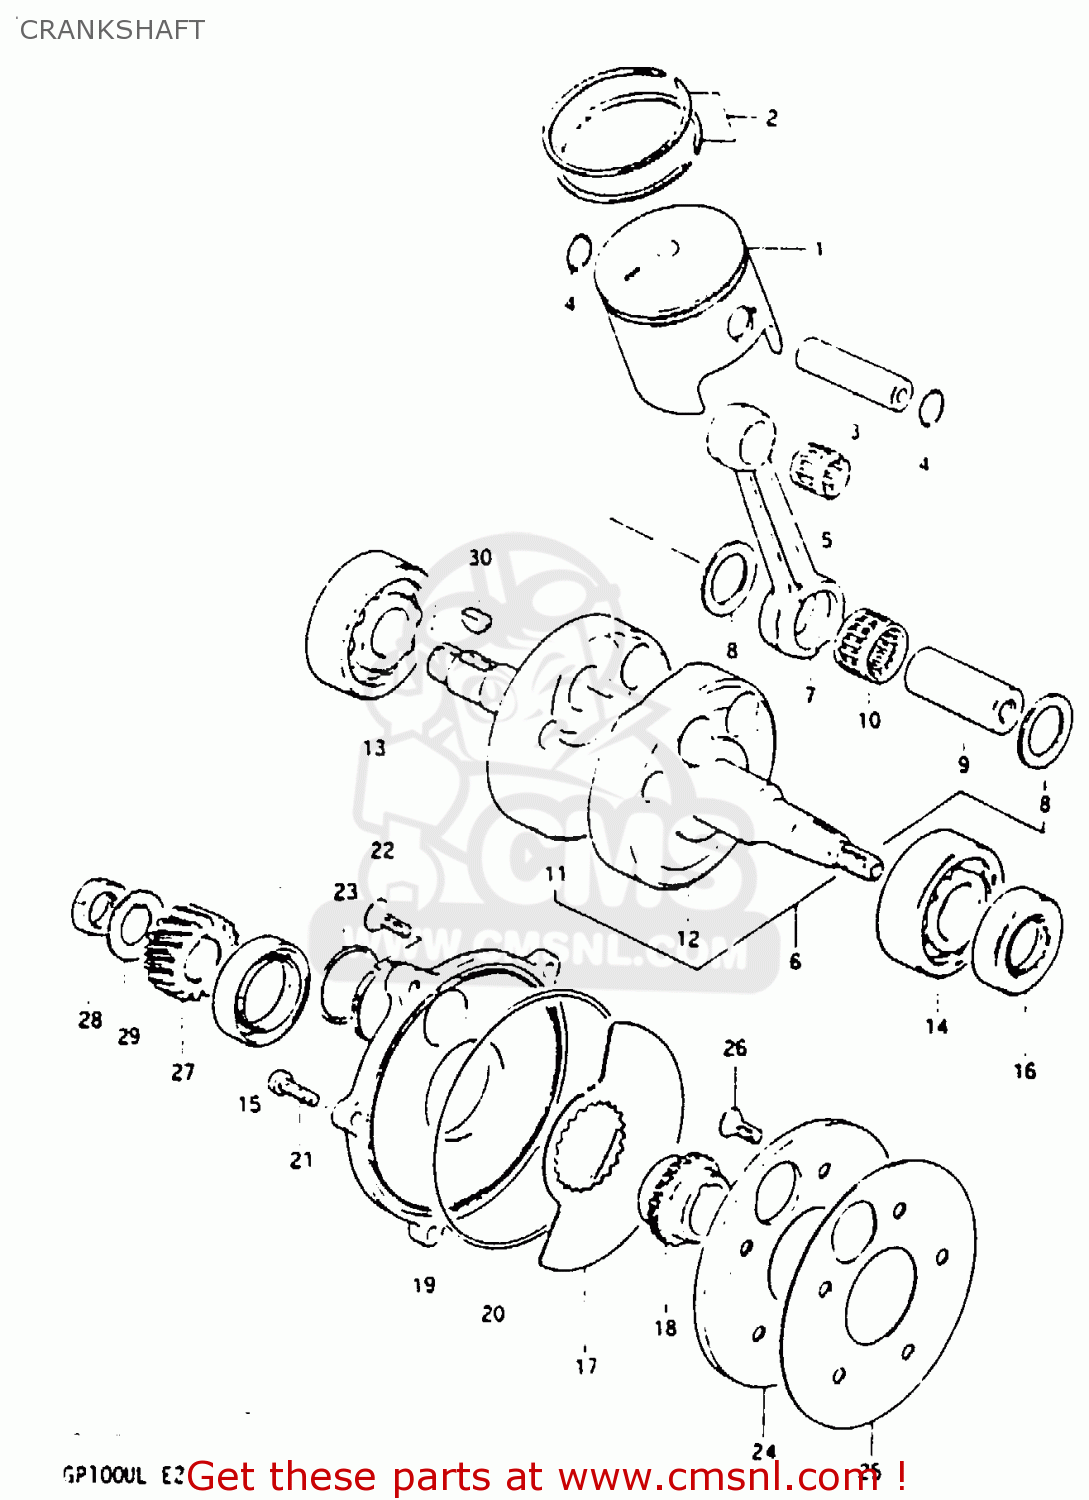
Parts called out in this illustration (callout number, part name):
1	PISTON
2	RING SET,PISTON
3	PIN,PISTON 14MM
4	RING,SNAP 14MM
5	BEARING 14X18X19.8
6	CRANKSHAFT ASSY
7	CONNECTING ROD
8	WASHER(19X32X1)
9	PIN,CRANK
10	BEARING(19X25X16)
11	CRANKSHAFT,R
12	CRANKSHAFT, LH
13	BEARING(20X52X15)
14	BEARING
15	SEAL,OIL(30X44X7)
16	SEAL,OIL(25X44X7)
17	PLATE,CRANKSHAFT VALVE
18	GUIDE, VALVE
19	SEAT, OUTER VALVE
20	O RING(D:2,ID:108.6)
21	SCREW
22	SCREW
23	O RING(D:2.4,ID:28.7)
24	SEAT,CRANKCASE INNER VALVE
25	GASKET,VALVE SEAT INNER (NAS)
26	SCREW
27	GEAR,PRIMARY DRIVE
28	NUT
29	WASHER
30	KEY
